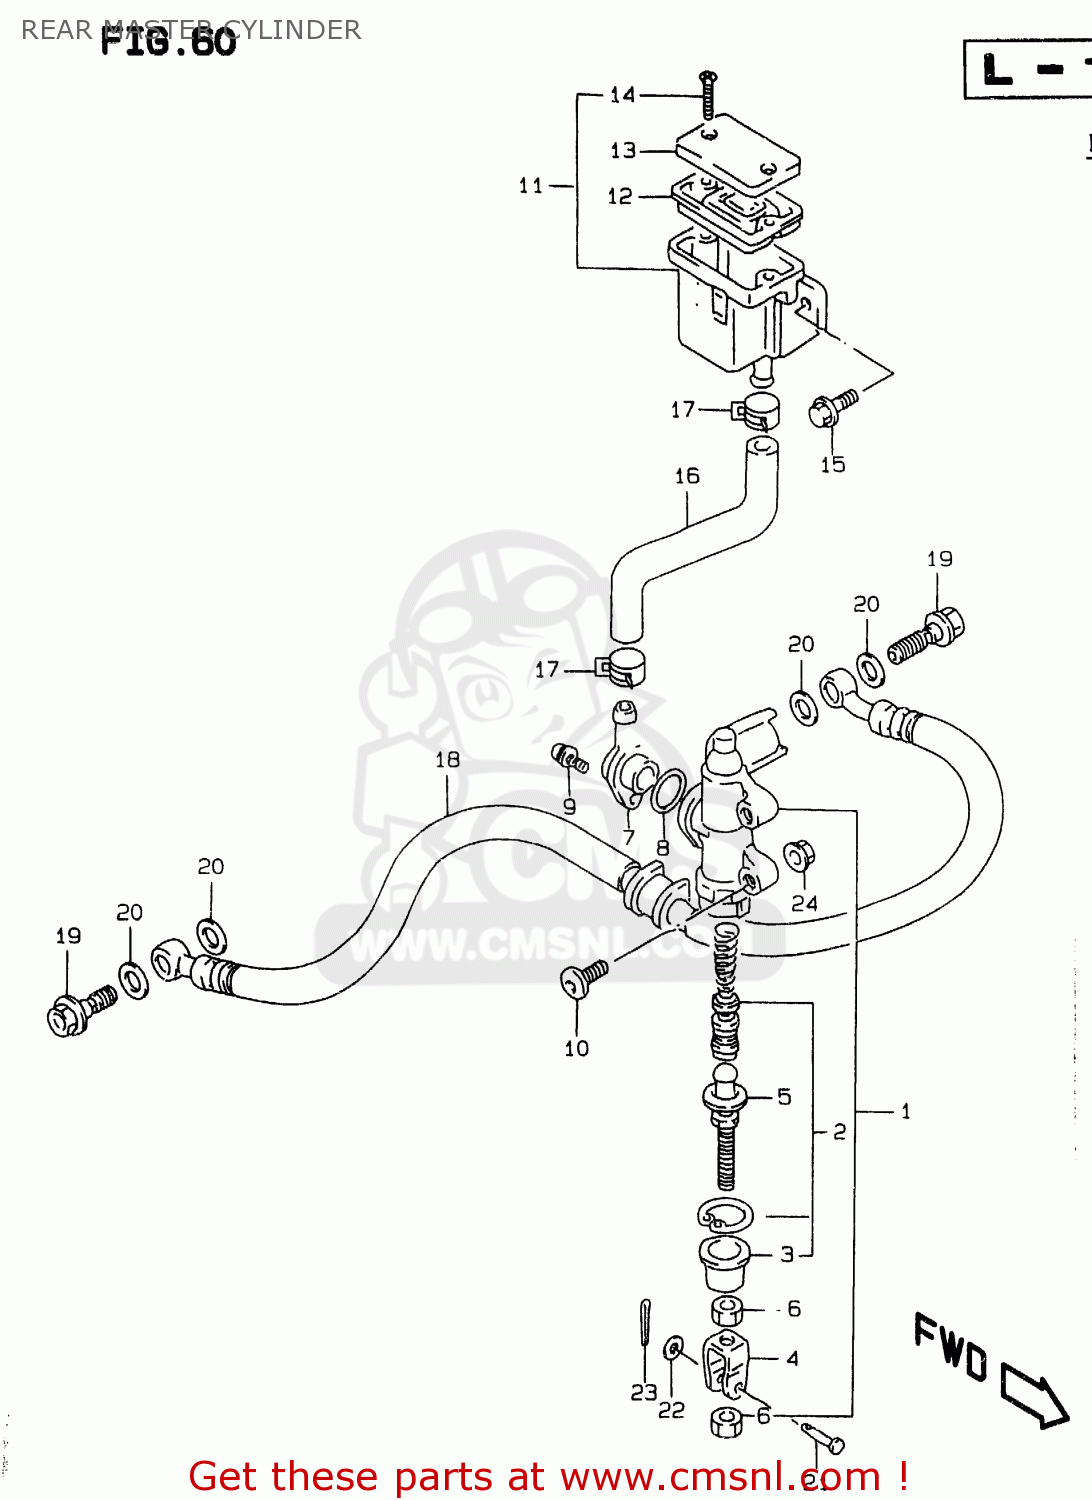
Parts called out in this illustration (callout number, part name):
1	CYLINDER ASSY,RR MASTER
2	PISTON/CUP SET
3	BOOT
4	YOKE
5	ROD,PUSH
6	NUT
7	CONNECTOR
8	O RING
9	SCREW
10	SCREW(6X30)
11	TANK ASSY,RESERVOIR
12	DIAPHRAGM
13	CAP
14	SCREW
15	BOLT
16	HOSE,RESERVOIR TANK
17	CLIP
18	HOSE,RR BRAKE
19	BOLT UNION
20	WASHER(10X15X1.5)
21	PIN
22	WASHER
23	PIN
24	NUT
